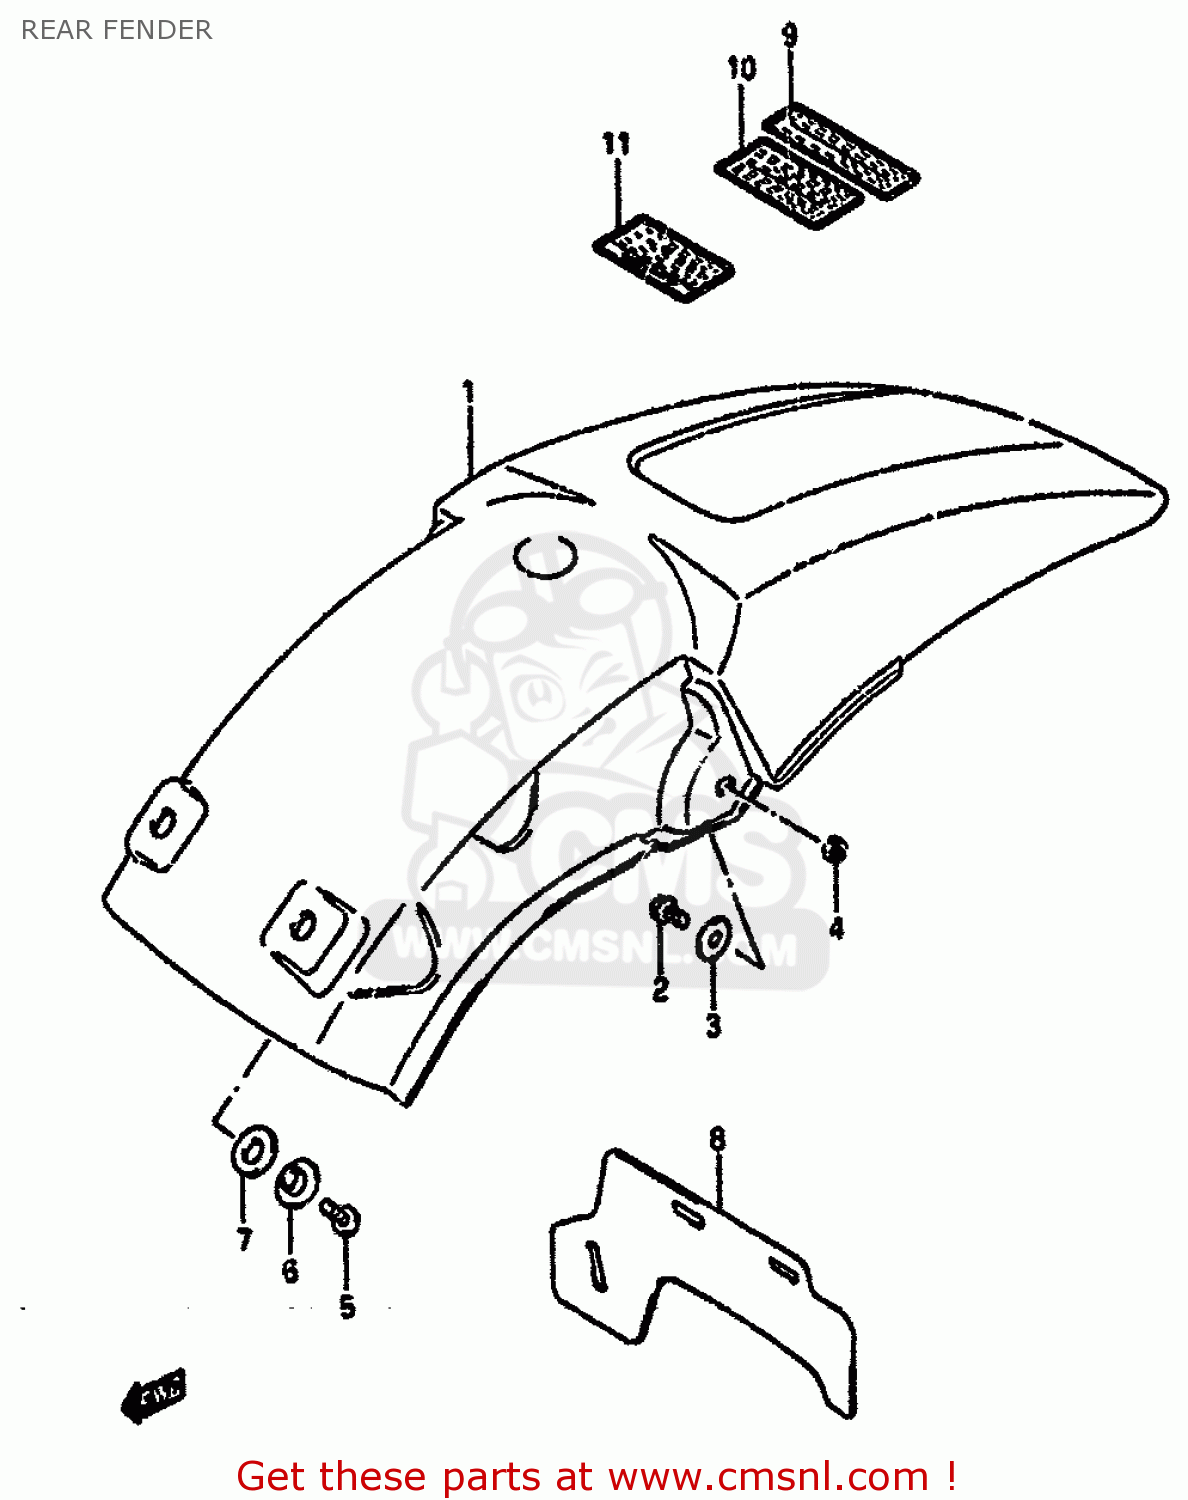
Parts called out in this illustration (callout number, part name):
1	FENDER,REAR
2	BOLT
3	WASHER (6.5X29X1.6)
4	NUT 6MM
5	SCREW
6	WASHER
7	WASHER(10.5X20X2.5)
8	MUDGUARD,RR FENDER
9	LABEL,WARNING
10	LABEL,WARNING
11	LABEL
